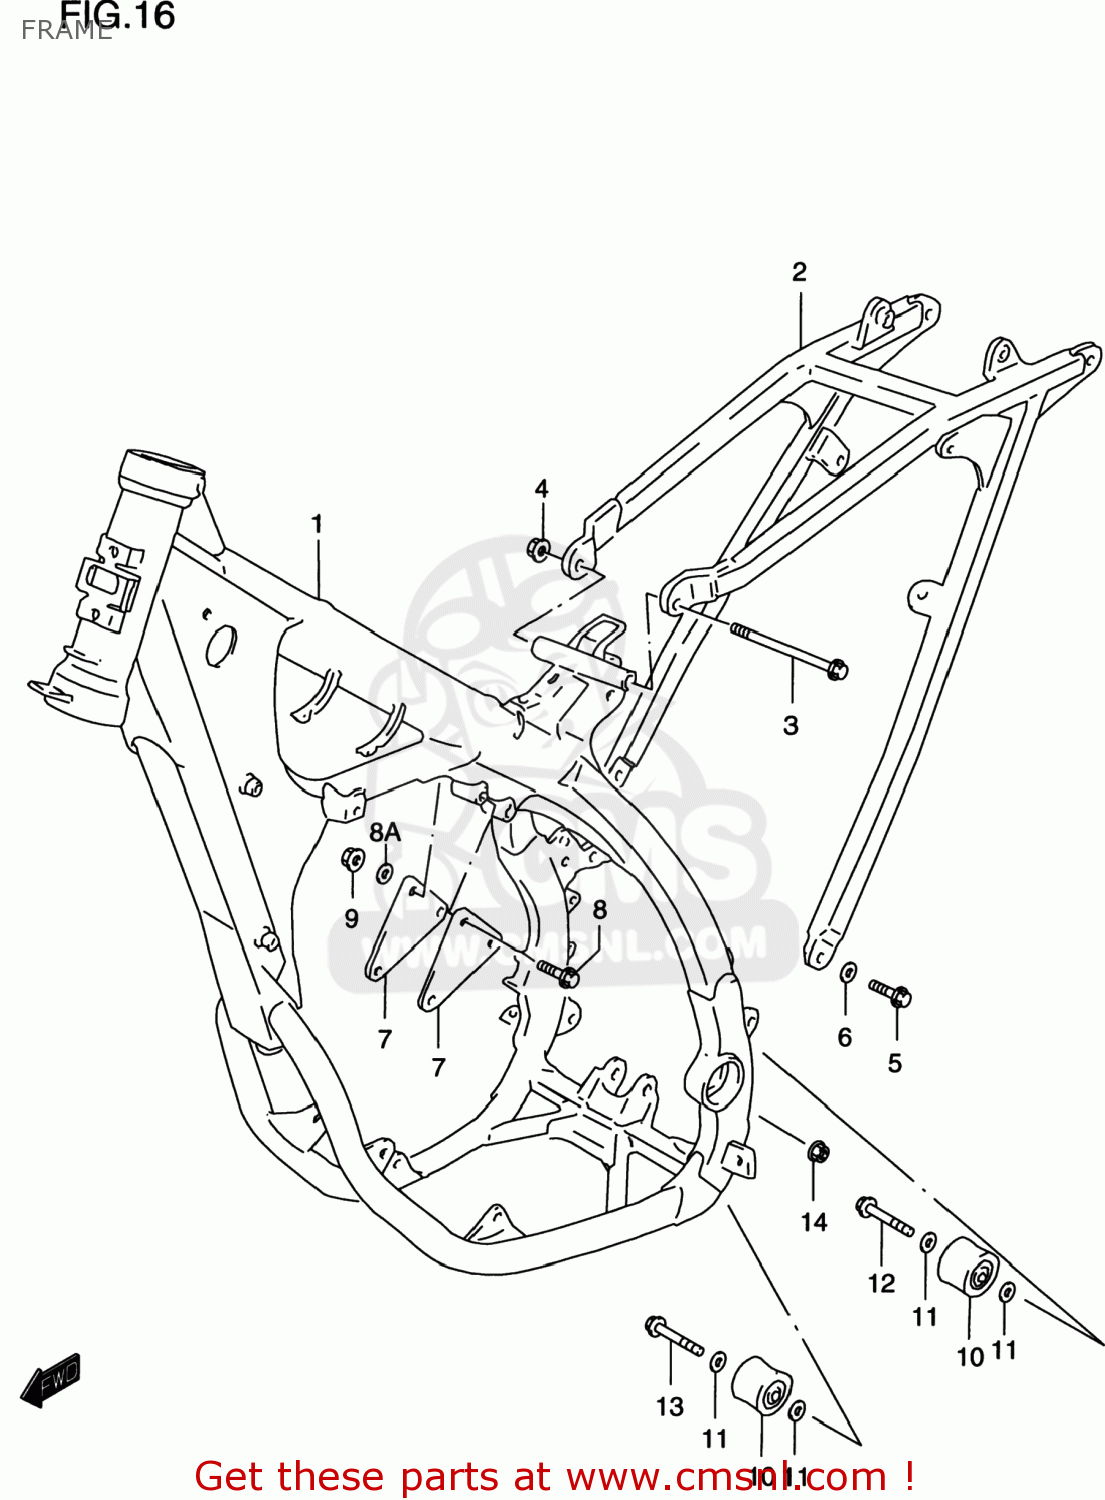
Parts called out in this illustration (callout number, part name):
1	FRAME COMP
2	RAIL,SEAT
3	BOLT(8X120)
4	NUT
5	BOLT 8X16
6	WASHER
7	PLATE,ENG MTG UPR
8	BOLT(8X41)
8A	WASHER
9	NUT
10	ROLLER,CHAIN
11	WASHER
12	BOLT(8X41)
13	BOLT(8X45)
14	NUT
